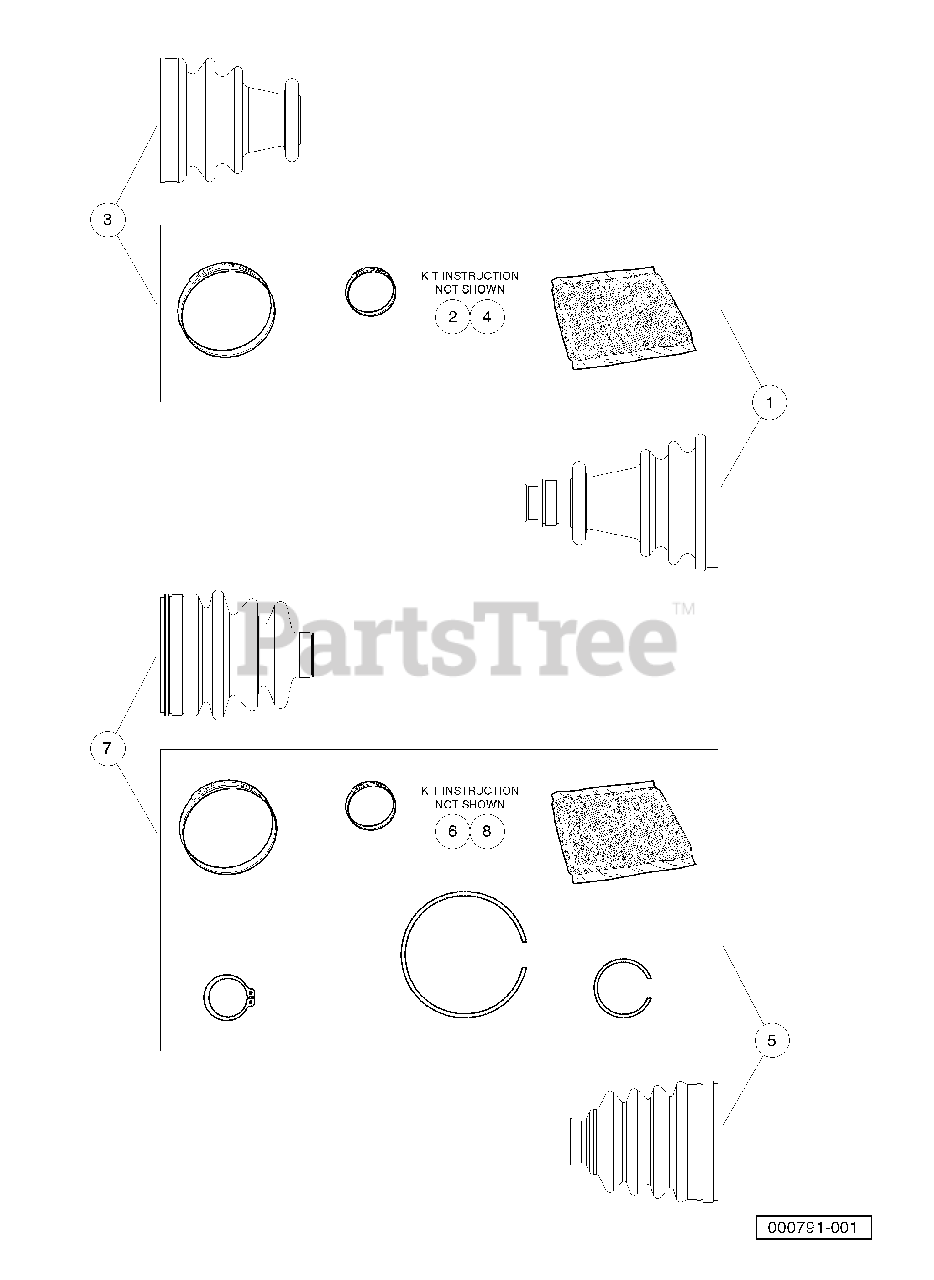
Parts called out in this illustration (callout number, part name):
1	Boxed Outboard Boot Kit
2	Half Shaft Boot Instl. Instr.
3	Boxed Inboard Boot Kit
4	Half Shaft Boot Instl. Instr.
5	Kit, Outer Boot, Gen 2
6	Instructions, Boot Replacement
7	Kit, Inner Boot, Gen 2
8	Instructions, Boot Replacement
